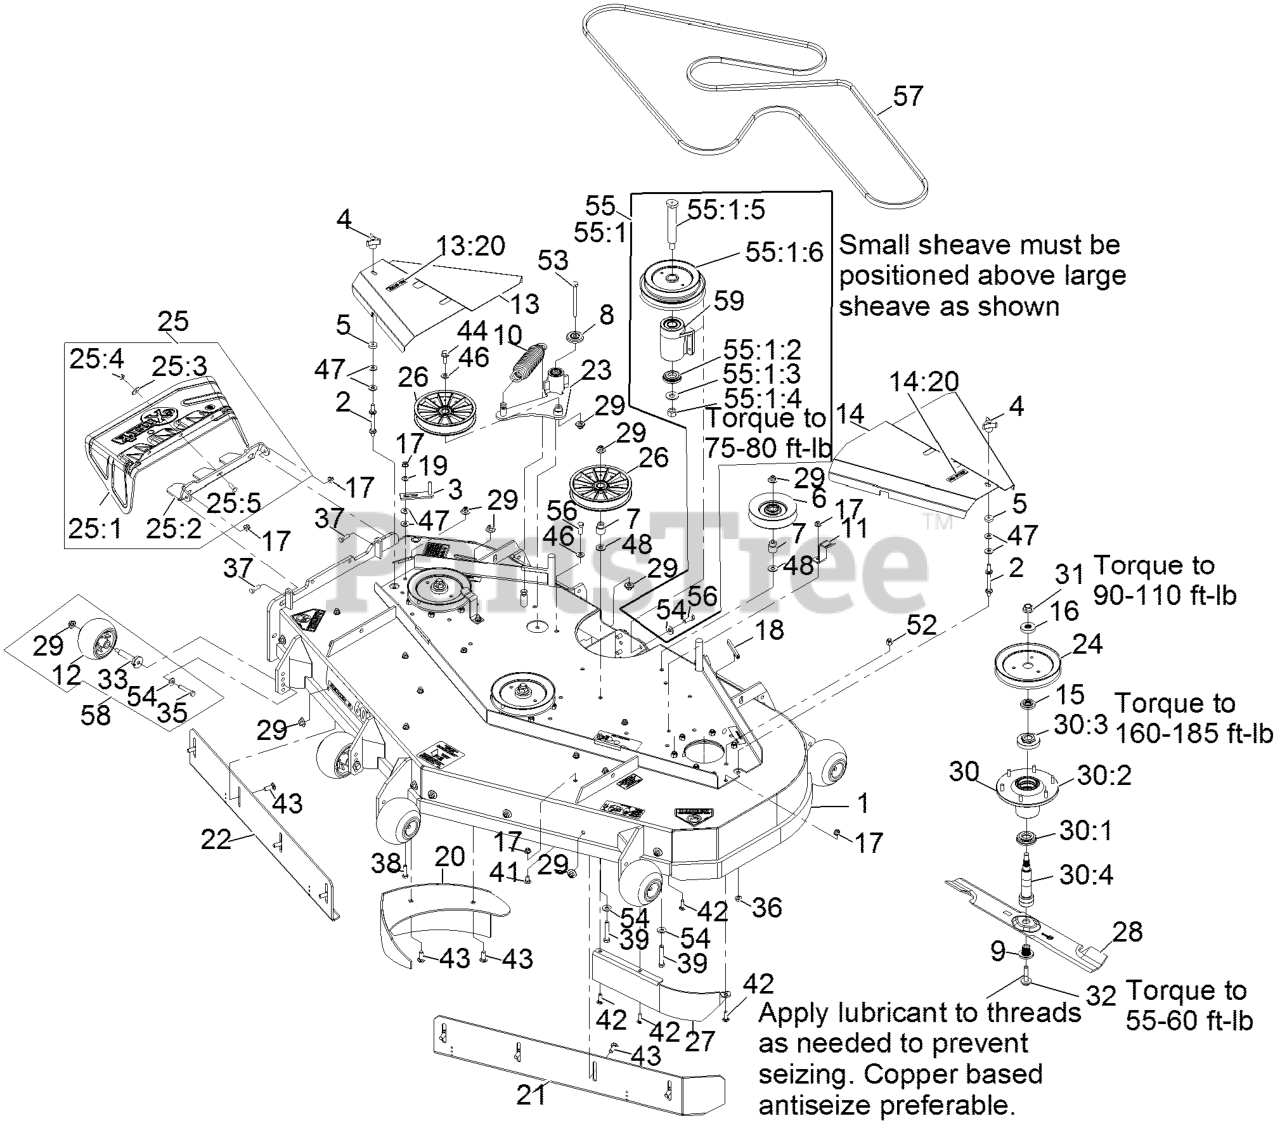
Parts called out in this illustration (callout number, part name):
1	ASM, DECK 605 W/DECALS
2	STUD-SHIELD, BELT (SHORT)
3	GUIDE-BELT
4	KNOB-3 PRONG
6	PULLEY-IDLER
7	BUSHING-IDLER
8	GUARD-TOP
9	BUSHING,SPLINED
10	SPRING-EXTENSION
11	LATCH,BELT SHIELD
12	ROLLER-SCALP, ANTI
13	SHIELD, BELT RH 605 W/DEC
13:20	DECAL,NO STEP
14	SHIELD, BELT LH 605 W/DEC
14:20	DECAL,NO STEP
15	SPACER,SPLINED STEPPED
16	SPACER,SPLINED
17	NUT-HF, NI
18	STRIP-SEAL
19	WASHER-SPRING
20	WLD,DOGLEG 605
21	WLD,BAFFLE FRT ADJ LH 605
22	WLD,BAFFLE FRT ADJ RH 605
23	KIT, IDLER ARM W/BEARINGS
24	SHEAVE, BLADE DRIVE 6.13
25	ASM, DISCHARGE CHUTE
25:1	CHUTE,DISCHARGE LZ
25:2	HINGE,DISCHARGE CHUTE
25:3	WASHER-FLAT
25:4	NUT-HF, NI
25:5	SCREW-CARR
26	PULLEY,IDLER 6"
27	BAFFLE,SCROLL 605
28	Blade-Extreme 2, 20.75
28	Blade-High Lift Solid, 20.75
28	Blade,High Lift Notched 20.75
29	Nut-Nyloc 3/8-16 Flg
30	ASM,SPINDLE HOUSING
30:1	GUARD,BOTTOM
30:2	ASM,CUTTER HOUSING
30:3	NUT, SPINDLE 7/8-14
30:4	SPINDLE,DOUBLE SPLINE
31	NUT-FLANGE, CENTERLOCK
32	SCREW,SEMS 1/2-20 X 2.19
33	AXLE, ROLLER
35	SCREW-HH 3/8-16 X 3 3/4 GR 8
37	SCREW-HH
38	SCREW-HH
39	SCREW-HH
41	SCREW-CARR
42	SCREW-CARR
43	SCREW-CARR
44	SCREW-HHF
46	WASHER-FLAT
47	WASHER-FLAT
48	WASHER-FLAT
52	NUT-LOCK, NI
53	SCREW-HH
54	WASHER-BELLEVILLE
55	KIT,JACKSHAFT 60/72-3750
55:1:2	SPACER-GUARD, BOTTOM
55:1:3	WASHER-SPRING
55:1:4	NUT-HEX
55:1:5	JACKSHAFT
55:1:6	SHEAVE, JACKSHAFT DOUBLE
56	SCREW-HH
57	BELT,BLADE DRIVE
58	KIT, ANTI-SCALP ROLLER
59	KIT, JACKSHAFT ASSY
